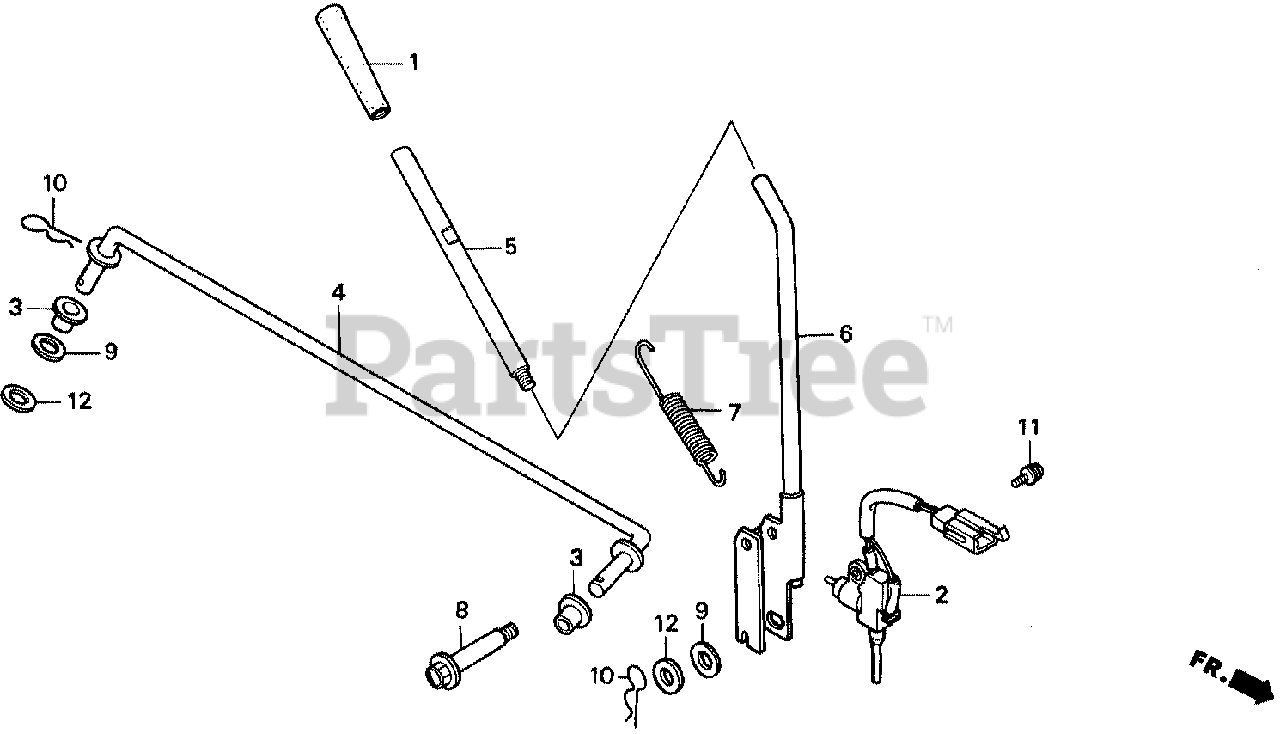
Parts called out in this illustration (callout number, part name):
1	GRIP, P.T.O. CLUTCH LEVER *Y121* (YELLOW)
2	SWITCH ASSY., P.T.O. CLUTCH
3	BUSH, P.T.O. ROD
4	ROD, P.T.O. CLUTCH
5	JOINT, P.T.O. CLUTCH LEVER
6	LEVER, P.T.O. CLUTCH
7	SPRING, P.T.O. CLUTCH
8	BOLT, P.T.O. CLUTCH LEVER
9	WASHER, P.T.O.
10	PIN, SNAP (7MM)
11	SCREW-WASHER (4X12)
12	WASHER, PLAIN (10MM)
